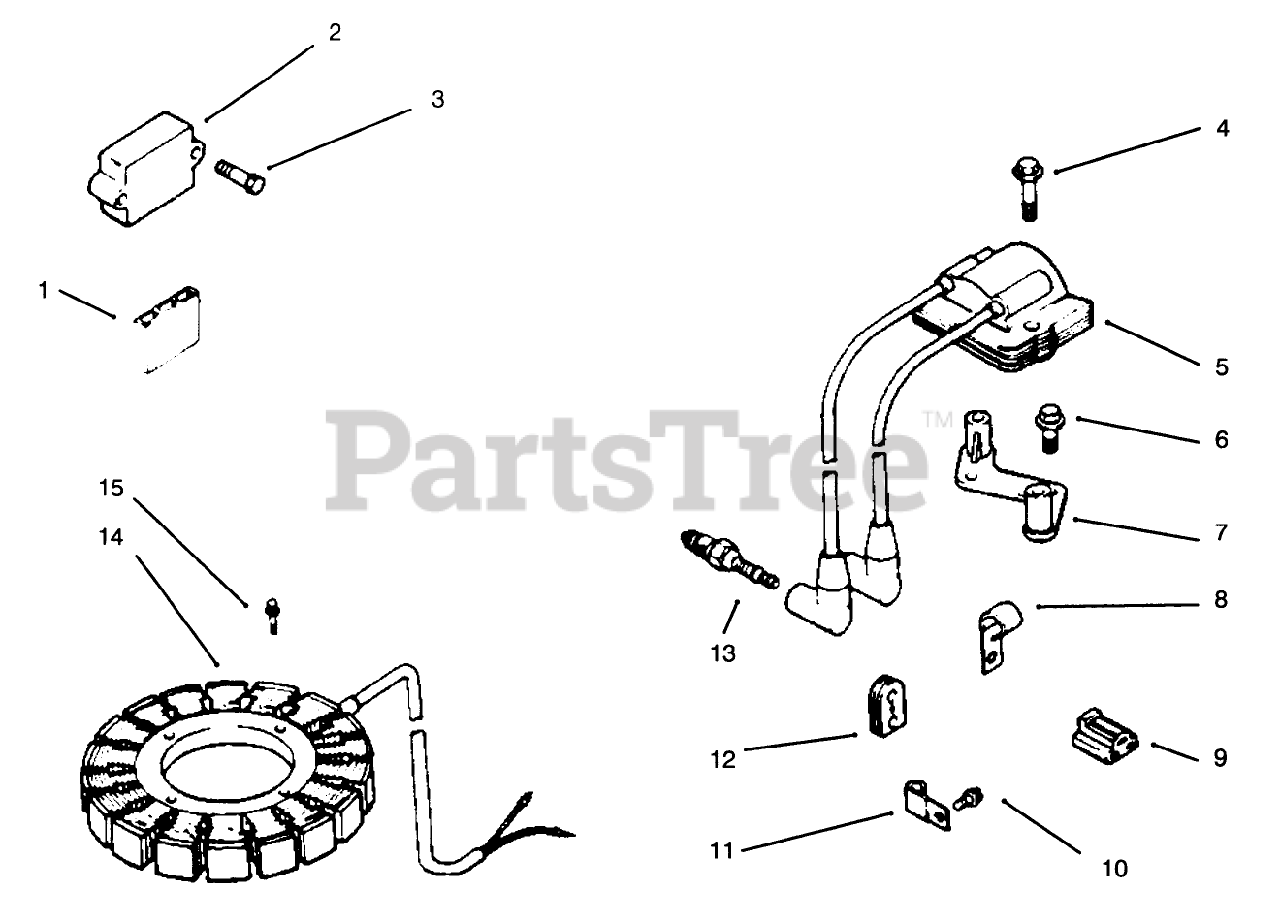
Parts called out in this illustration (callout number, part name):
1	Connector
2	Kit-Rectifier/Regulator (Incl. Ref. #3)
3	Screw
4	Screw-Hex. Washer Hd.
5	Module-Ignition
6	Screw-Hex. Washer Hd.
7	Bracket-Module
8	Clip
9	Connector
10	Screw
11	Clip
12	Grommet
13	Spark Plug
14	Screw
15	Kit-Stator (Incl. Ref. #15)
